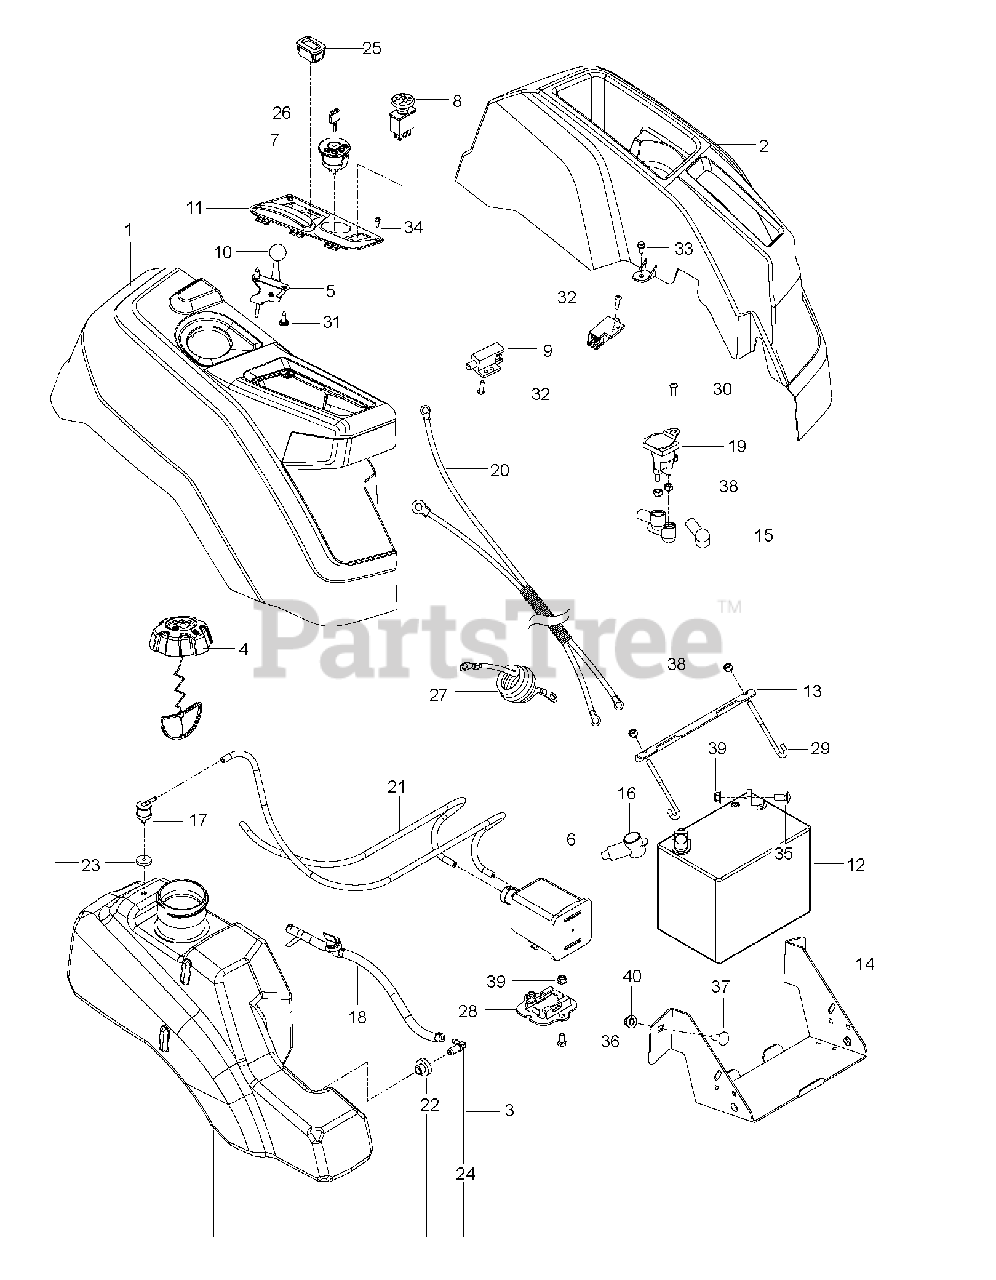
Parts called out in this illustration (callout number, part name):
1	CONSOLE.ASSY.RZ.REFRESH.RH
2	CONSOLE.LH.ASM
3	ASM.FUEL.TANK.LG.3".W/O SHIELD
4	CAP ASSY FUEL 3" GRAY
5	CABLE.THROTTLE.37"
6	CANNISTER, CARBON
7	RP IGNITION SWITCH
8	RP SWITCH.PTO.TERMINAL.STD.RED
9	SWITCH.INTLK.RZ.RFRSH.BUTTON
10	KNOB.ROUND.BALL.BLACK
11	CONTROL.PANEL.RZ.REFRESH.RH
12	BATTERY, 12 V 300 AMP
13	BRACKET.PNT.MOUNT.BATTERY.EDIP
14	BOX.PNT.BATTERY.RZ.EDIP
15	TERMINAL COVER
17	VALVE.FUEL.CHECK
18	FUEL.HOSE.SHUT.OFF.ASM.10".3"
19	SOLENOID.STARTER.BRASS.PLUNGER
20	HARNESS.BTTRY.CABLE.RZ.REFRESH
21	HOSE.3/16".VAPOR.LINE.33"LGTH
22	BUSHING OUTLET T
23	GROMMET.ROV.SENTEC
24	STEM FUEL TANK
25	GUAGE.SRVCMNDR.HRMTR.
26	KEY MLD GEN DELTA
27	CABLE POSITIVE, LONG
28	BRACKET, CANISTER
29	HOOK.J.BATTERY
30	SCR 1/4-20 X 5/8 BTN SKT HD ZD
31	SCREW.PAN.HEAD.#10
32	SCREW.BUTTONHD.10-24X1/2.(2 2)
33	SCREW
34	SCREW 6-19X.437
35	BOLT 5/16-18 X3/4 ZN/YEL GR 5
36	HCS 5/16-18 X 5/8 GR 5 ZD
37	RHSNB 3/8C X 1
38	LOCKNUT.NYLOC.1/4-20
39	5/16-18 NYLOC FLANGE NUT
40	NUT 3/8-16 HEX FLG NYLOC ZD
